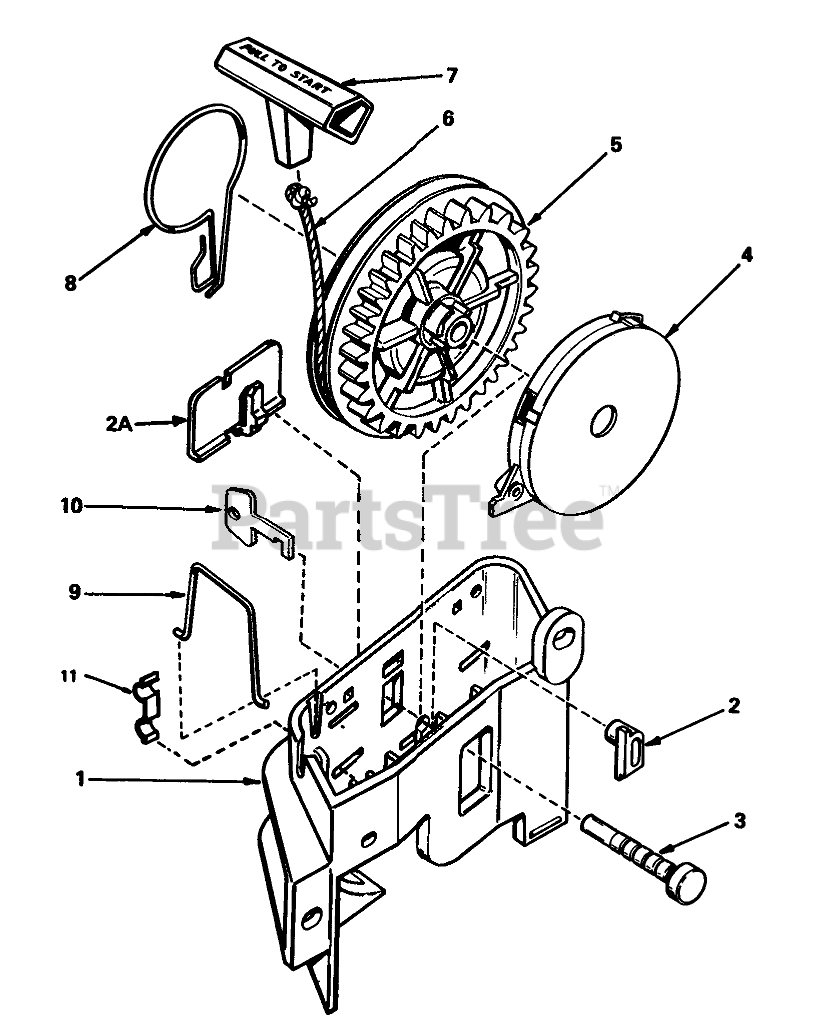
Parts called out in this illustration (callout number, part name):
1	Bracket Starter
2	Pawl, Locking Not used on all engine models)
2A	Clip, Starter Bracket (Used On Starters Not Equipped With Pawl, Ref. No. 2)
3	Pin-Pulley
4	Spring Assy., Rewind (Incl. #3)
6	Rope Starter (Length 65" & 9/64" Dia.)
7	Handle-Starter
9	Clip-Rope
10	Key (Not Used On All Engine Models
11	Washer-Thrust
